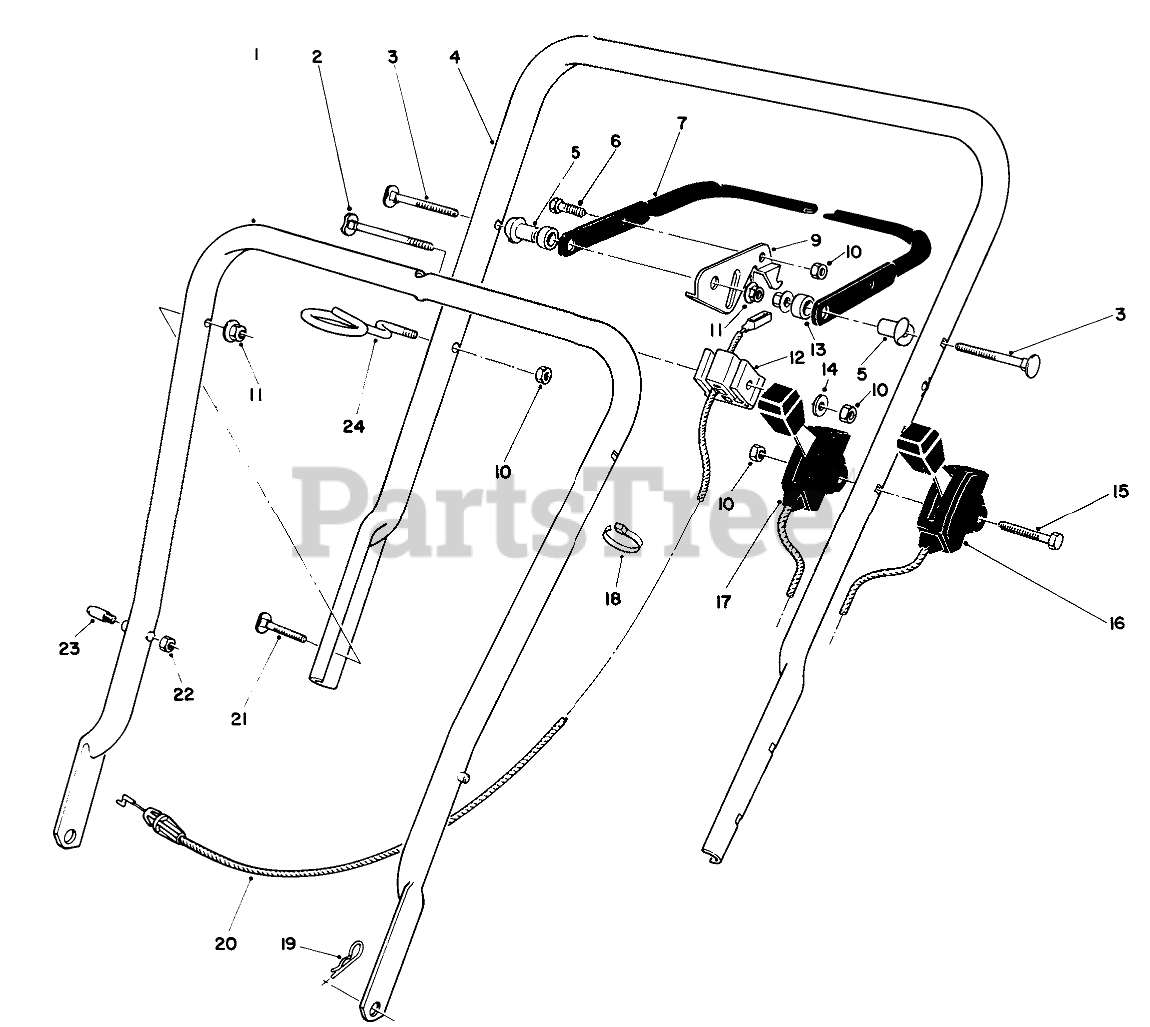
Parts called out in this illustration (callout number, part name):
1	Lower Handle Assembly
2	SCREW-HANDLE
3	SCREW-HANDLE
4	UPPER HANDLE
5	SPACER-SUPPORT
6	SCREW-HH
7	Bar-Control
9	CONTROL LEVER
10	NUT-LOCK, NI
11	NUT-LOCK NI
12	SUPPORT-CABLE
13	SPACER-NYLON
14	WASHER-FLAT
15	SCREW-HH
16	TRACTION CONTROL
17	THROTTLE CONTROL
18	TIE-CABLE
19	PIN-COTTER, HAIR
20	BRAKE CONTROL CABLE
21	SCREW-HANDLE
22	NUT-LOCK, NI
23	HANDLE PIN
24	GUIDE-ROPE
